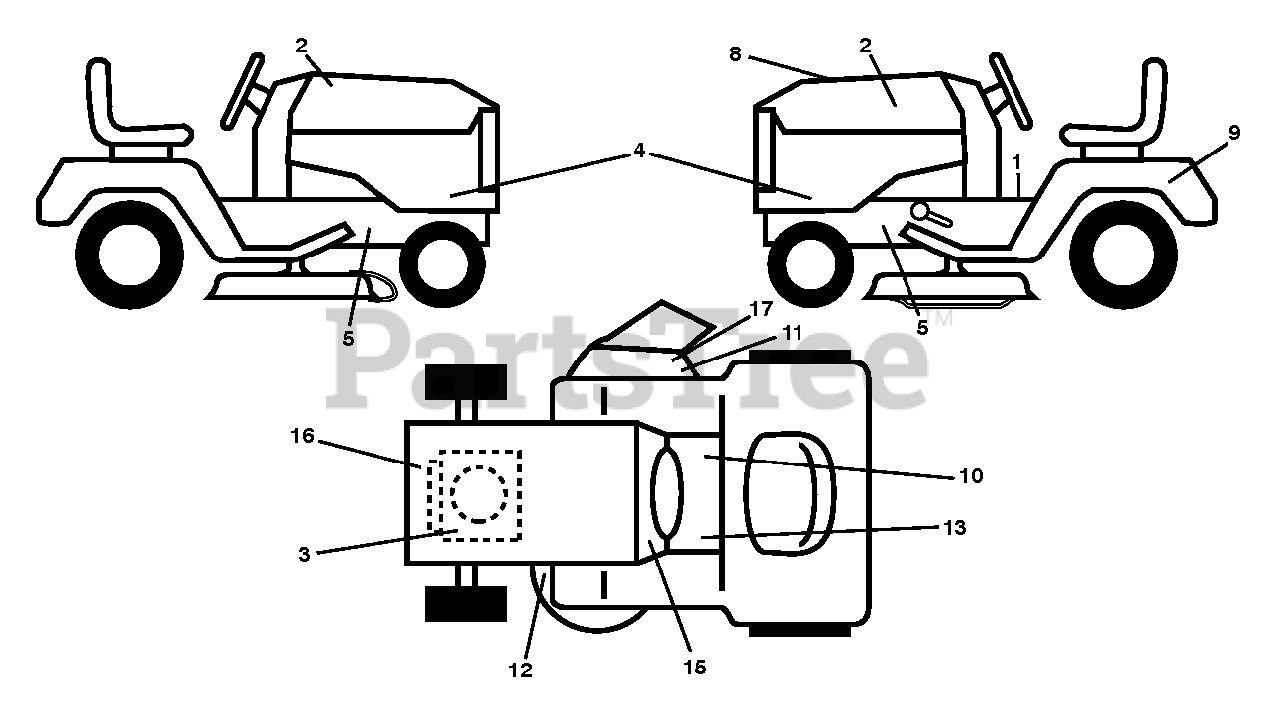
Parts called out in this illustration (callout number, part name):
1	DECAL.READ.OWN.MAN.SYMBOL.LT
2	DECAL.BADGE.170MM.TEXTLOGO.
3	DECAL.ENGINE.WARNING
4	DECAL.SDPNL.HUSQLT.TS138
5	DECAL.CHASSIS.HOT.MUFFLER
8	DECAL.RPL.BSM31.INTK.TLW.38.GE
9	DECAL BTRY SYMBOLS
10	DECAL.PARKING.BRAKE.SADDLE.LT
11	DECAL.DFLCTR.WARNNG.CTFNGR.SYM
12	DECAL.DECK.SCH.36,38,94.NONCR
13	DECAL.FNDR.SDLE.BRAKE.CLUTCH.6
15	DECAL.SNOWFLAKE.MS498.HUSQ
16	DECAL.ENG.B&S.HS.500CC.382338
17	DECAL, DECK DEFLECTOR, WARNING
